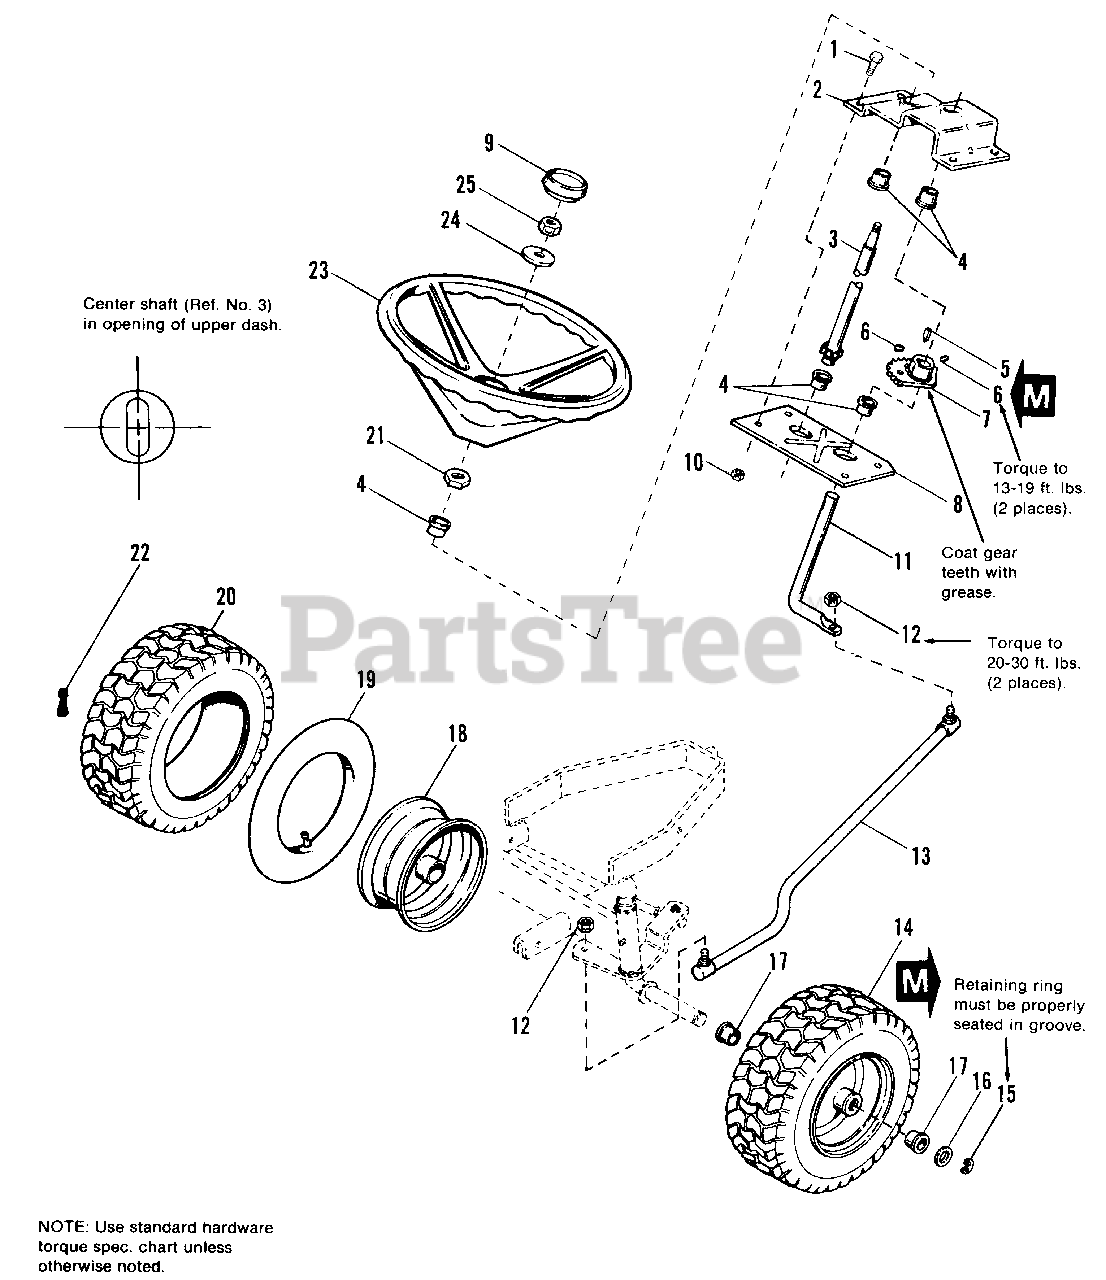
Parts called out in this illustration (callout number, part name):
1	CAPSCREW, Hex Hd., 5/16-18 x 3/4
2	PLATE, Steering
3	SHAFT ASSY., Steering
6	SETSCREW, 5/16-18 x 1/2
7	GEAR, Steering
8	PLATE, Base, Steering
9	CAP, Steering Wheel
10	LOCKNUT, Hex, Flange, 5/16-18
11	ROD, Steering
12	NUT, Special, 3/8-24
14	WHEEL & TIRE ASSY.
18	WHEEL ASSY.
19	TUBE, 4.10/3.50-6 (For Service Only)
20	TIRE, 13 x 6.50-6 (Carlisle)
20	TIRE, 13 x 6.50-6 (Goodyear)
21	WASHER, Hex
22	VALVE STEM & CAP
23	WHEEL, Steering
24	WASHER, Compression
25	LOCKNUT, Hex, 5/16-18
